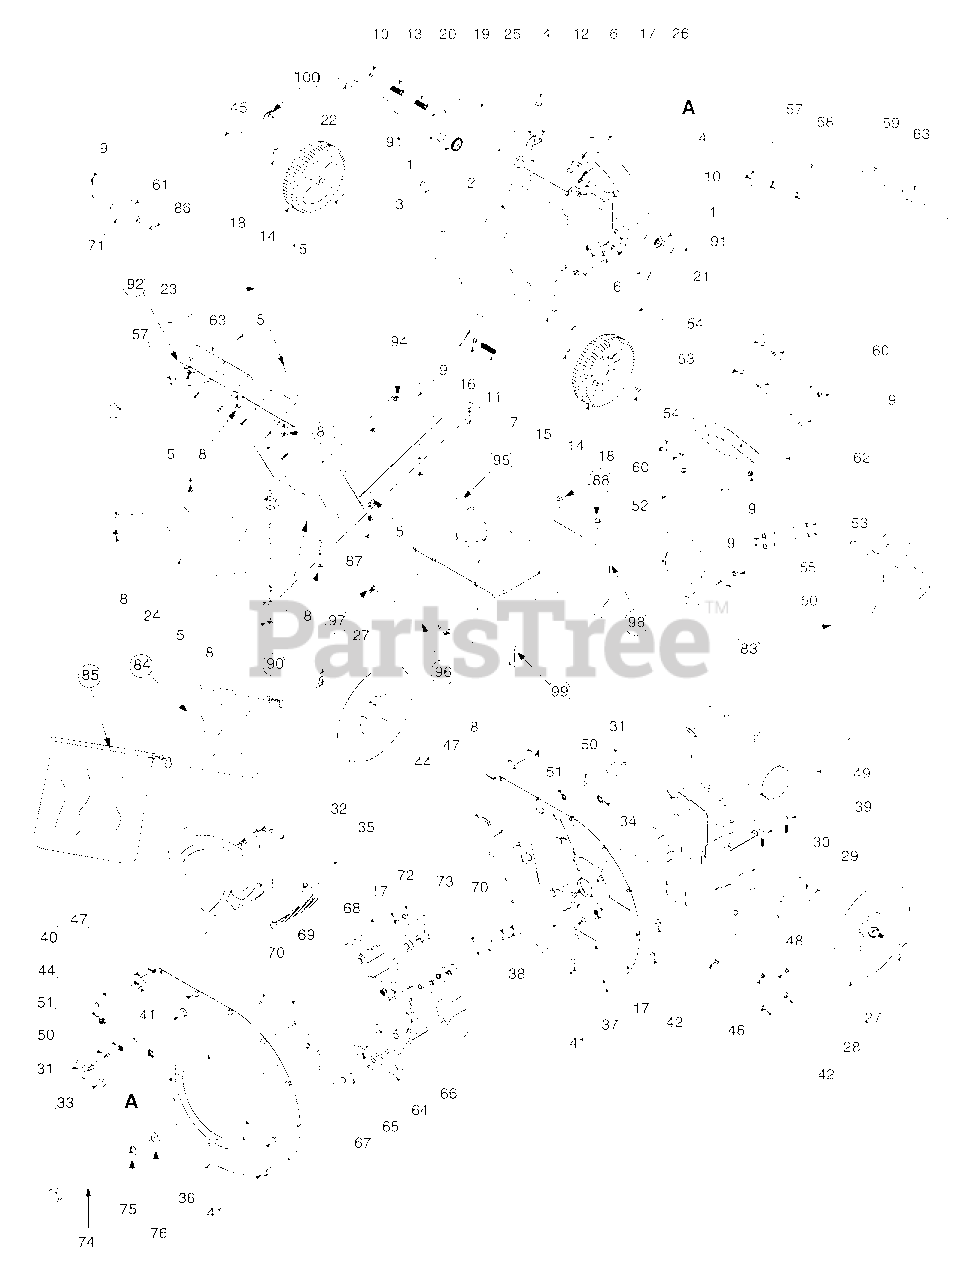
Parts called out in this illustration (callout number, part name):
1	Stop Washer
4	TL Hex Screw 5/16-18 x 0.5"
5	Button Head Screw
6	Hex Lock Nut 5/16-18
7	Axle Shaft
8	Hex Lock Flanged Nut 1/4-20
9	Internal Cotter Pin
10	Cap Nut
11	Compression Spring
12	Torsion Spring
13	Hopper Door Spring
14	Complete Wheel: Grey
15	Flat Washer
16	Flat Washer
17	Lock Washer
18	Push Cap
19	Rod: 5/16 Dia.
20	Hopper Door Rod
21	Lock Rod
24	Lower Hopper: Polo Green
28	Complete Wheel Grey
29	Flat Washer: 5/8 I.D.
30	Shredder Axle
31	Knob Assembly
32	Discharge Chute Assembly: Polo Green
33	Hex Bolt 1/2-13 X 5" Gr. 5
34	Hex Center Lock Nut 1/2-13
36	Outer Flail Housing Assembly
37	Inner Flail Housing Assembly
38	Hex Bolt 5/16-24 X 0.75" Gr. 5
39	Hex Bolt 5/16-18 X 1.75" Gr. 5
40	Hex Screw 1/4-20 X 3.75"
41	Hex Bolt 5/16-18 X 0.75"
42	Hex Lock Flange Nut 5/16-18 Gr. 5
44	U Nut 5/16-18
45	Flap Control Rod
46	Bell Washer
47	Hinge Spacer: Chute
50	Belleville Washer
51	Speed Nut
54	Hex Bolt 1/4-20 x .625
55	Hex Nut 5/16-18
57	Rivet
58	Chipper Chute
59	Chute Flap
60	Flat Washer
61	Spiral Pin
64	Flail Blade
65	Retaining Clip
66	Spring Roll Pin
67	Clevis Pin
68	Impeller Assembly
69	Shredder Blade
70	Flat Hd. Scr. 5/16-24 x .75"
71	Arm Bracket Assembly
72	Hex Top Lock Nut
73	Chipper Blade
74	Hex Patch Bolt 3/8-24 X 2.25" Gr. 8
75	Lock Washer
76	Flat Washer
83	Tamper Plug
84	Chip Bag
85	Leaf Bag
86	Rubber Washer
87	Rubber Flap
88	Screw
90	Flap Retaining Bail
91	Shoulder Screw
95	Fuel tank
96	Fuel Line Hose
97	Hose Clamp
